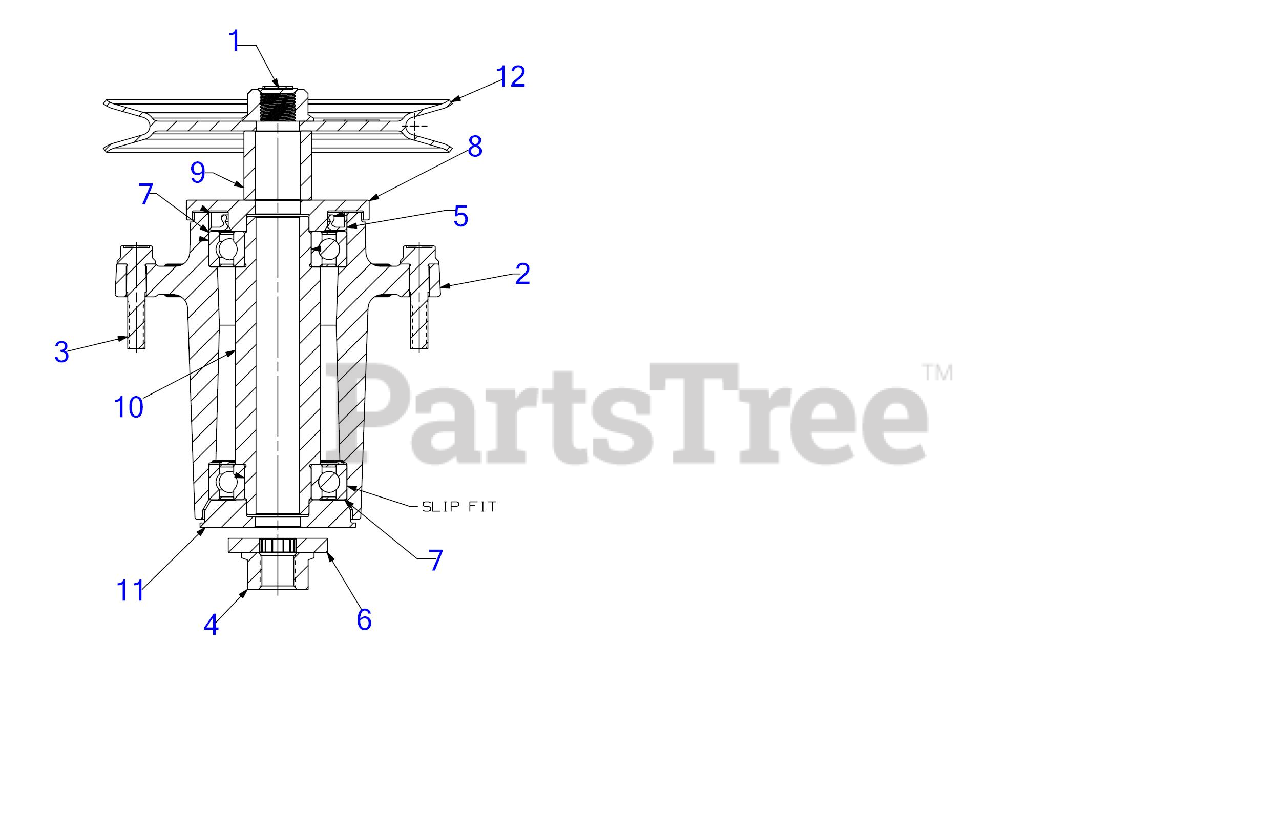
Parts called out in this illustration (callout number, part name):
1	SPINDLE SHAFT
2	SPINDLE HOUSING
3	BOLT 5/16-18 x 1.50 GR5
4	FLANGE NUT - 5/8-18 GDE 8
6	FLAT WASHER - SPECIAL
7	SEALED BALL BEARING 30x62x16
8	DECK SPINDLE SPACER
9	SPACER 0.760 X 1.50 X 1.24
10	SPACER 0.760 X 1.50 X 3.484
11	SPACER 0.790 X 2.75 X 0.486
12	V-PULLEY 6.107 DIA
